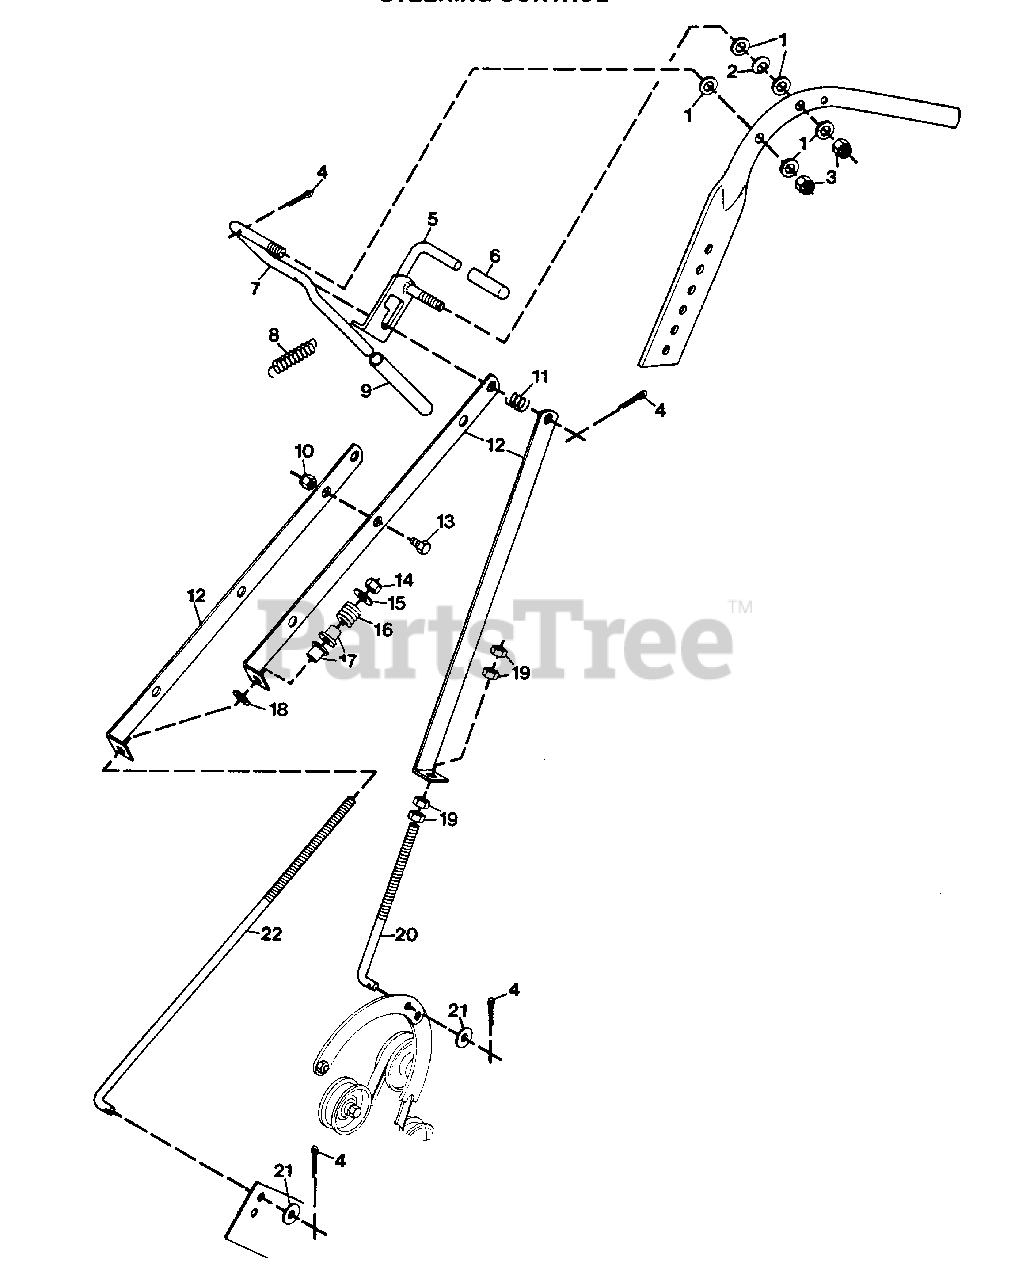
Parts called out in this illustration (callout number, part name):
1	WASHER, NYLON .375X.75.06
2	WASHER, SPRING .375 I.D.
3	NUT, LOCK 3/8-16
4	PIN, COTTER .09X.75
5	WELDMENT, CLUTCH BRAKE
6	TIP, BRAKE LOCK LEVER
7	LEVER, HAND CLUTCH
8	SPRING, EXTENSION
9	GRIP, HAND CLUTCH LEVER
10	NUT, LOCK 1/4-20
11	SPRING, COMPRESSION
12	STRAP, CLUTCH-BRAKE
13	BOLT, HEX 1/4-20X.50
14	NUT, LOCK 5/16-18
15	WASHER, FLAT .344X.688X.065
16	SPRING, COMP. 1X.78X338
17	BUSHING, NYLON .32X.437X.204
18	RING, CIRCULAR PUSH-ON
19	NUT, HEX 5/16-18
20	ROD, CLUTCH
21	WASHER, FLAT .375X1.125X.065
22	ROD, BRAKE LOWER
